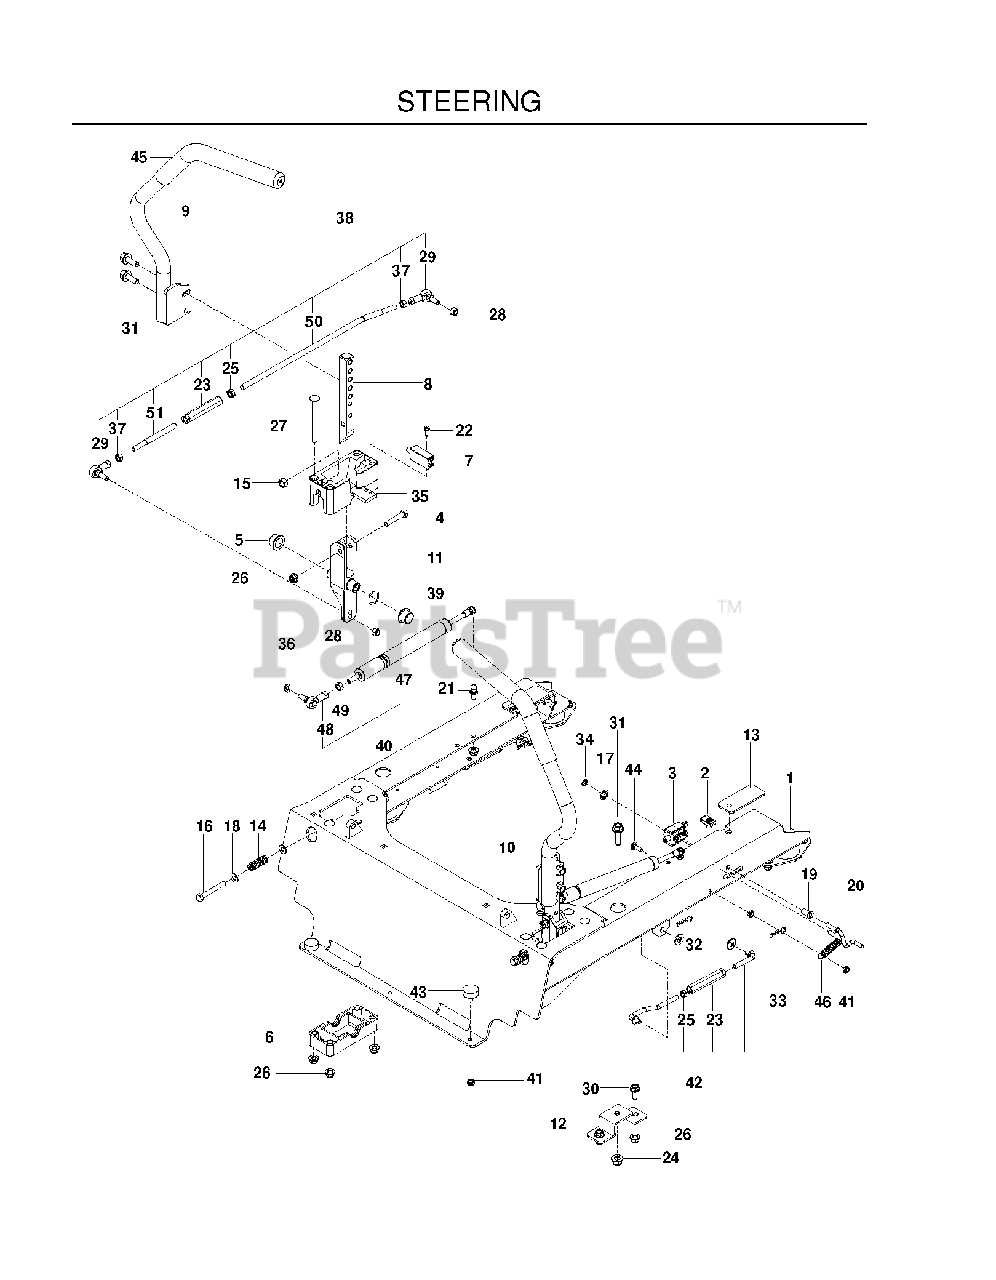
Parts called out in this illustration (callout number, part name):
1	FRAME, SEAT MOUNT, BLUE
2	U-CLIP 5/16-18 NUT RETAINER
3	SWITCH, BRAKE 3P
4	HCS 5/16C X 1 3/4
5	BEARING, FLANGE
6	BLOCK, LOWER
7	SWITCH, INTERLOCK
8	LEVER, MOTION
9	LEVER, W/GRIP, RT
10	LEVER, W/GRIP, LT
11	LEVER, CONTROL
12	MOUNT, MID-SECTION, BLK
15	NUT 5/16C HEX
16	HCS 5/16-18 X 2 1/2 TPBLT
17	BOLT RETAINER 3/8
18	FLAT WASHER 5/16 SAE
19	BUSHING, 1/4 FLANGE
20	LINK, SWITCH
21	10MM BALL STUD
22	SCREW #10 X 1/2 SELF TAPPING
23	TURNBUCKLE, 3/8
24	NUT 3/8-16 HEX FLG NYLOC ZD
25	NUT 3/8-24 JAM
26	5/16-18 NYLOC FLANGE NUT
27	RHSNB 5/16-18 X 3-3/4 GR 5 ZD
28	NUT 5/16F NYLOC
29	SPHERICAL ROD END, RH
30	HHFS 5/16-18 X 3/4
31	HHFS 3/8-16 X 1 GRD 5 ZD
32	WASHER 3/8 SAE FLAT
33	HAIRPIN #2
34	NUT PUSH
35	BLOCK, UPPER
36	WASHER 5/16 LOCK
37	NUT 5/16F
39	WASHER, .825 X 1.087, WAVE
40	ASSEMBLY, DAMPENER
41	JAM NUT 1/4C
42	ASSEMBLY, SEAT STRUT
44	RHSNB 1/4C X 3/4
45	GRIP - DRIVE LEVER
46	SPRING, EXTENSION
47	DAMPENER
48	ROD END
49	NUT M8 X 1.25 STD HEX
50	LINKAGE, CONTROL, FT
